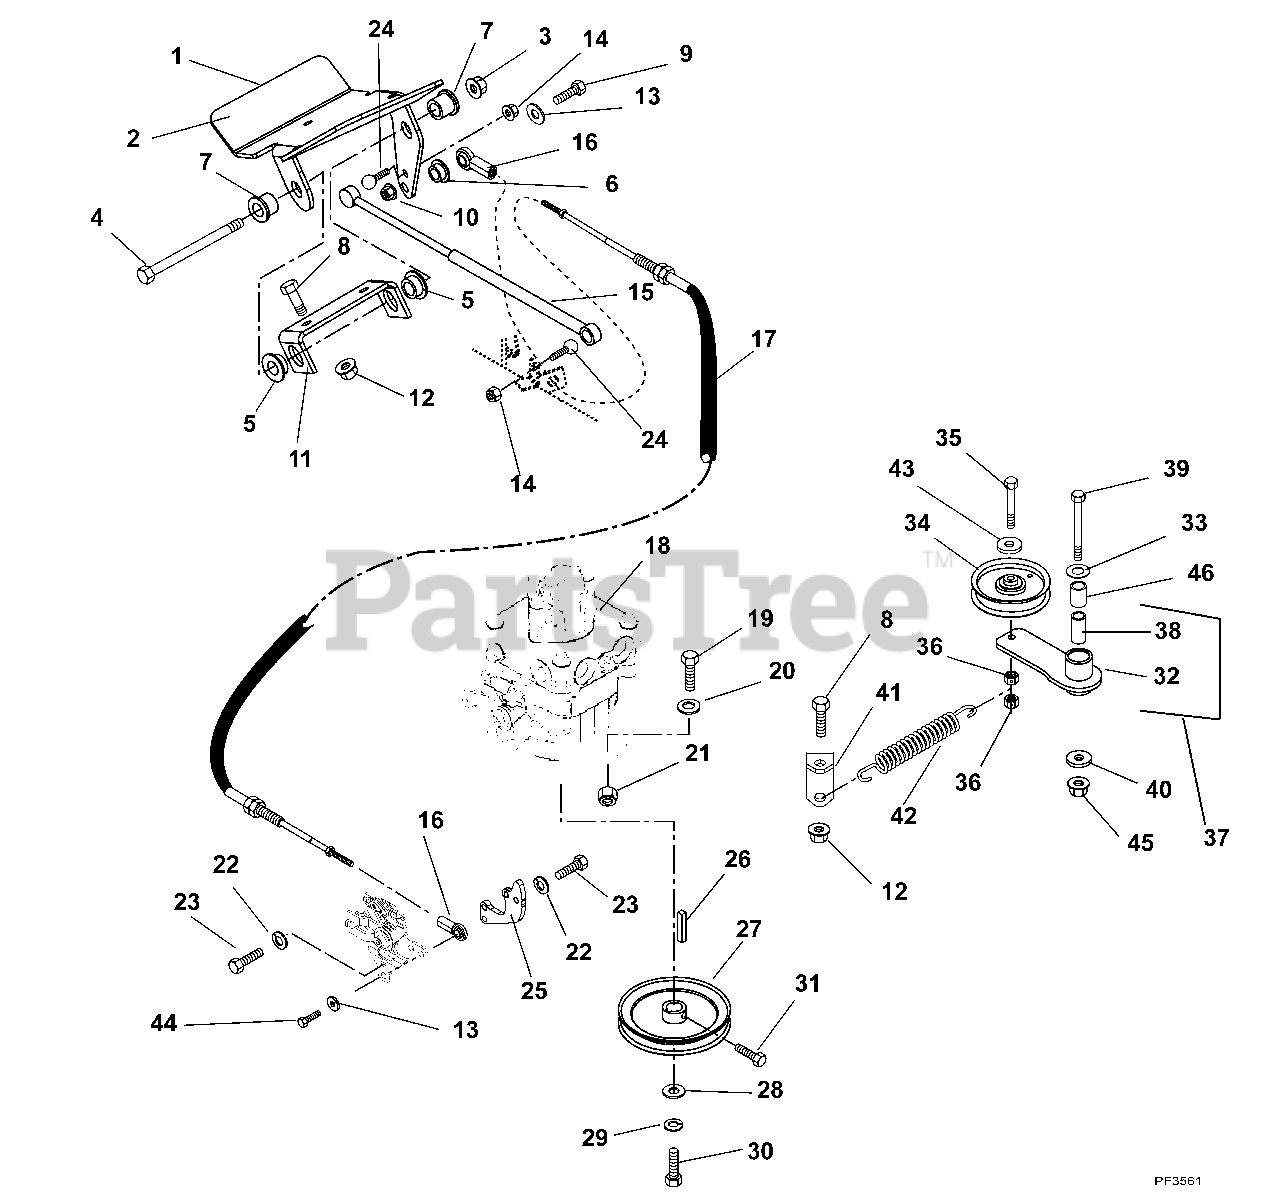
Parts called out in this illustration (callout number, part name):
1	Pedal, Direction Control
2	Pad, Foot Clutch Pedal
3	Nut, Locking-Top-Flange .50-13
4	Bolt, Hex .50-13 x 6.50 Grade 5
5	Bushing, Flange - Nylon .762 x 1.00 x .58 x 1.48
6	Bushing, Flange .265 x .437 x .250 x .750
7	Bushing, Flange-Nylon .515 x .75 x .745 x 1.00
8	Bolt, Hex .38-16 x 1.00 Grade 5
9	Bolt, Hex .25-20 x 1.00 Grade 5
10	Nut, Locking Top Flange .25-20
11	Bracket, Control Pedal
12	Nut, Locking Top Flange .38-16
13	Washer, Flat Steel .28 x .62 x .065
14	Nut, Locking Top Flange .31-18
15	Dampener Control
16	Rod End, Female .25 RH
17	Cable, Forward-Reverse Control
18	Pump (Bi-Directional RTN) (see page 17)
19	Bolt, Hex .50-13 x 1.50 Grade 5
20	Washer, Flat-Steel .531 x 1.06 x .095
21	Nut, Locking Top Flange .50-13
22	Washer, Locking .31 x .078
23	Bolt, Hex .31-18 x .50 Grade 5
24	Stud, Ball
25	Plate, PM320 Return Cam
26	Key, Straight 5mm x 5mm x 30mm
27	Sheave, Pump
28	Washer, Flat Steel .281 x 1.000 x .063
29	Washer, Locking .25 x .062 Regular
30	Bolt, Hex M6 x 1.0 x 12 EP30 YZ
31	Bolt, Hex .25-20 x .50 Grade 5
32	Weldment Arm, Idler
33	Bushing, Spacer .505/.500 x .999/.996 x 2.05/2.03
34	Idler, V 4.00 x .38
35	Bolt, Hex .38-16 x 2.25 Grade 5
36	Nut, Locking Center .38-16
37	Assembly, Idler Arm
38	Bushing, 1.00 x 1.125 x 1.937
39	Bolt, Hex .50-13 x 4.00 Grade 5
40	Washer, Flat Steel .515 x 1.625 x .250
41	Anchor, Spring Idler
42	Spring, Extension
43	Washer, Flat-Steel .406 x .812 x .065
44	Bolt, Hex .25-20 x 1.25 Grade 5
45	Nut, Locking Center .50-13
46	Washer, Flat Steel .511 x 1.441 x .125
